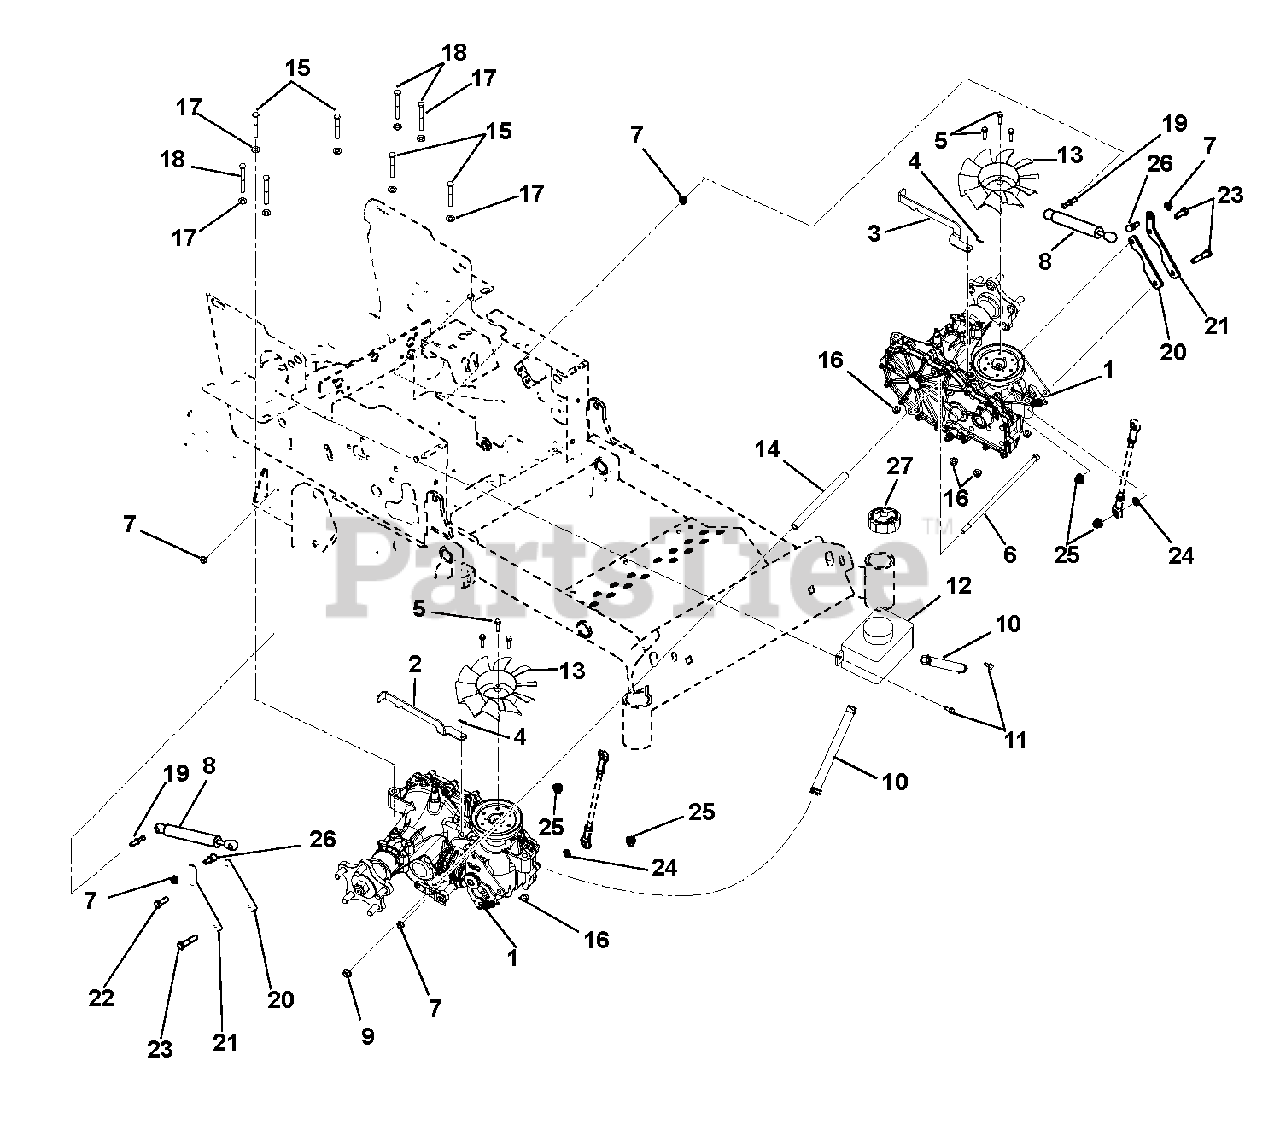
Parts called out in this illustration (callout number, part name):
1	Transaxle, 3100 Series – Left Hand (page 16)
1	Transaxle, 3100 Series – Right Hand (page 18)
2	Right Hand Dump Valve Lever – Black
3	Left Hand Dump Valve Lever – Black
4	Pin, Hair, Internal .06 x .18 x .77
5	Screw, Tapping .25-20 x 1.00 Hex Washer Head Thread
6	Bolt, Hex .38-16 x 11.00 Grade 5
7	Nut, Top Lock Flange
8	Damper, Stabilus
9	Nut, .38-16 Nyloc Flange
10	Assembly, Hydro Overflow Tank Hose
11	Screw, Tapping .25-20 x .50 Hex Washer Head Thread
12	Tank, Expansion
13	Fan, Cooling
14	Spacer, .38 ID x 5/8 OD x 7.72
15	Bolt, Hex .31-18 x 2.50 Grade 5
16	Nut, Nyloc Flange .312-18
17	Washer, Flat Steel .344 x .688 x .065
18	Bolt, Hex .31-18 x 3.00 Grade 5
19	Ball Stud, Threaded
20	Plate, Reinforcement
21	Plate, Damper Mounting
22	Bolt, Hex .38-16 x 1.00 Grade 5
23	Bolt, Hex 3/8-16 x 1.75 Grade 5
24	Washer, Locking .38 x .094
25	Nut, Nyloc Flange 3/8-16
26	Ball Stud, Threaded
27	Cap, Hydro Reservoir Replacement
